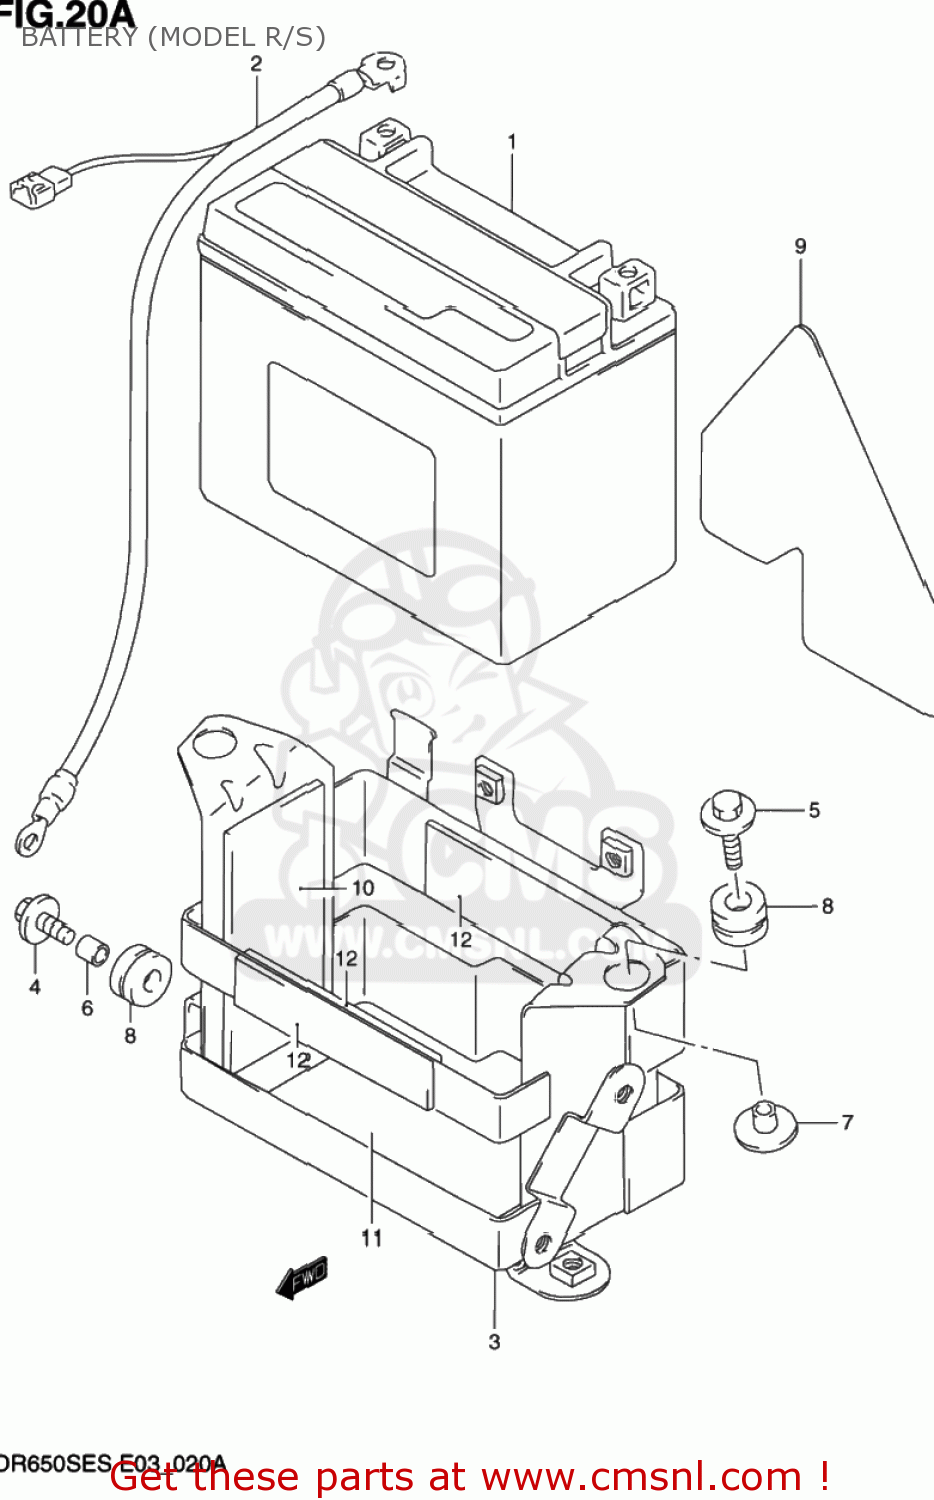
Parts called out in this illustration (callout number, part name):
1	BATTERY ASSEMBLY (12V) YTX
2	WIRE,BATTERY MINUS LEAD
3	HOLDER,BATTERY
4	BOLT 6X16
5	BOLT(6X25)
6	SPACER(6.1X9X7.5)
7	PLATE,BATTERY HOLDER
8	CUSHION
9	HEAT PROTECTOR,BATTERY
10	PROTECTOR(170X95X3.0)
11	PROTECTOR(170X95X3.0)
12	PROTECTOR(170X95X3.0)
